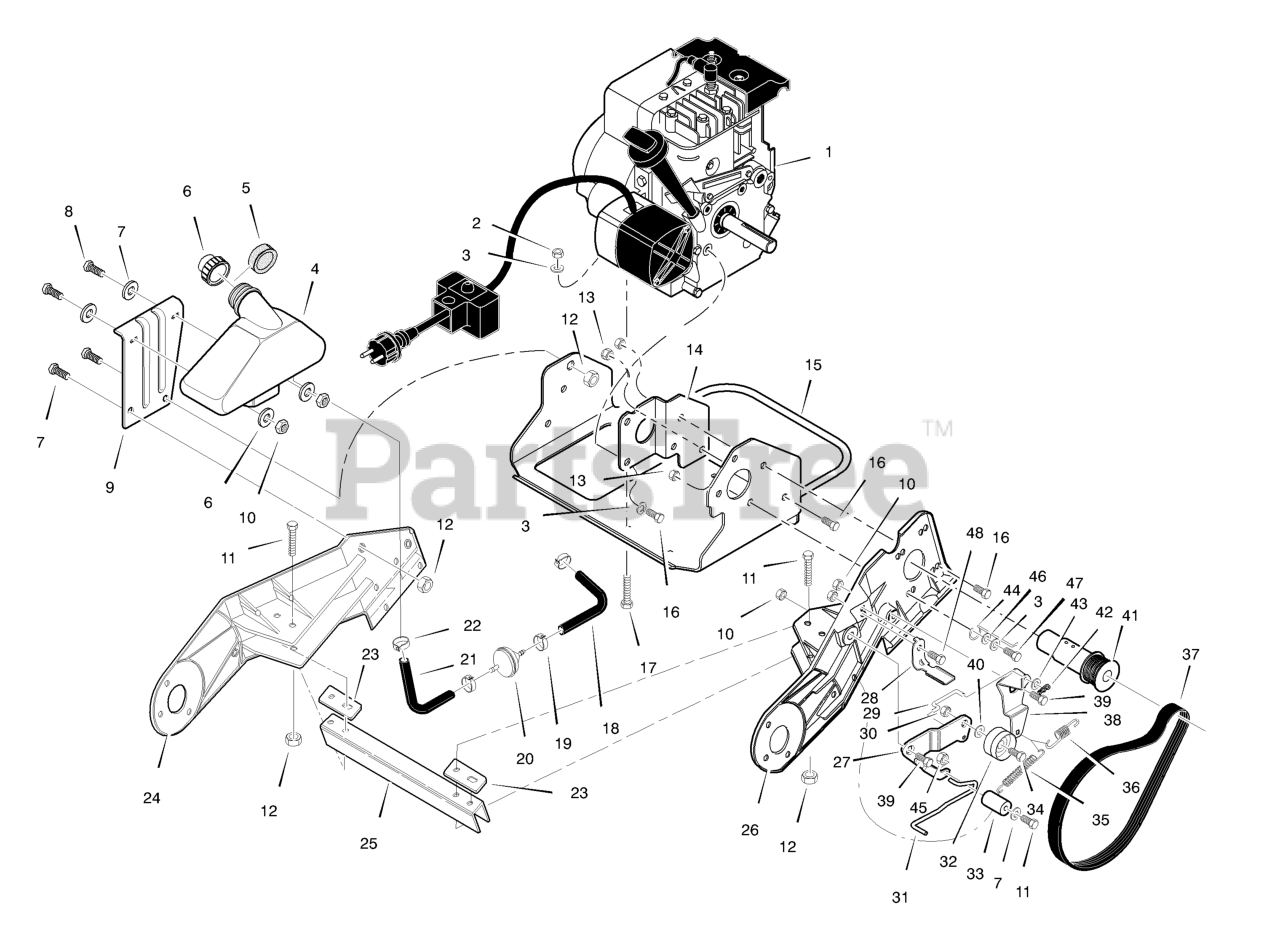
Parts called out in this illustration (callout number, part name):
1	ENGINE
2	NUT, 5/16-18
3	WASHER, SPTLK
4	TANK, FUEL
5	RING, FOAM FURL TANK
6	CAP, FUEL
7	WASHER, FLAT
8	SCREW, 1/4-20 x 0.75
9	BRACKET, FUEL TANK
10	NUT, 1/4-20 REGHEXCTRLK
11	SCREW, 1/4-20 x 2.00
12	NUT, 1/4-20 REGHEX
13	NUT, 5/16-18 HEXCTRLK
14	BRACKET, ENGINE
15	CRADLE, WELDMENT
16	BOLT, 5/16-18 x 0.75
17	BOLT, ENGINE MOUNT
18	TUBING, FUEL LINE 6 IN.
19	CLAMP, FUEL LINE
20	FILTER, FUEL LINE
21	TUBING, FUEL LINE 8 IN.
22	CLAMP, HOSE SCREW
23	PLATE, BOLTING SUPPORT
24	FRAME, RH. SIDE STEEL SUPT.
25	CHANNEL, FRAME SUPPORT
26	FRAME, LH. SIDE STEEL SUPT.
27	LF ARM, IDLER BRACKET
28	LF PAD, BRAKE
29	ROD, CLUTCH LINKAGE
30	NUT, 3/8-16 JAM CTRLK
31	WIRE, BRAKE
32	PULLEY, IDLER
33	ROLLER, PINCH
34	SCREW, 3/8-16 x 1.50
35	SPRING, EXTENSION
36	SPRING, EXTENSION
38	ARM, IDLER PIVOT
40	WASHER, FLAT
41	PULLEY, ENGINE
42	PIN, COTTER
43	WASHER, FLAT #8
44	GUIDE, BELT
45	NUT, 1/4-20
46	WASHER
48	SCREW, 1/4-20 x 0.63
